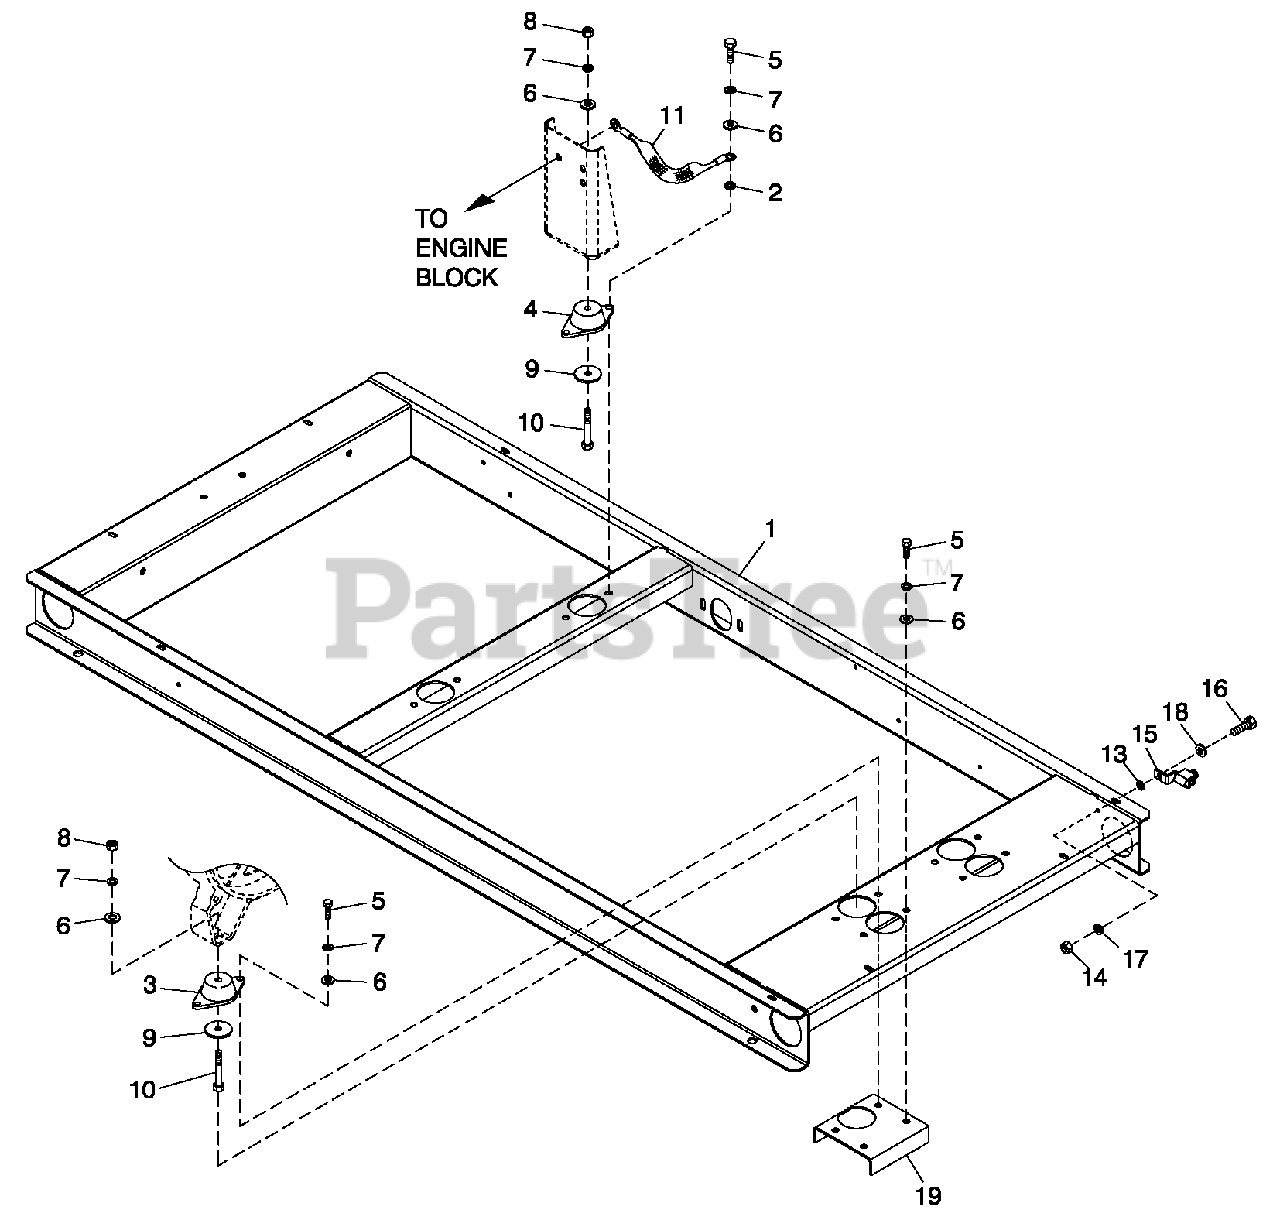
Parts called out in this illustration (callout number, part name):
1	MOUNTING BASE1.6L 2007 C1
2	WASHER SHAKEPROOF EXT 5/16 STL
3	DAMPENER VIBRATION
4	VIB. ISO. 70-75 DURO
5	SCREW HHC M8-1.25X 20 G8.8
6	WASHER FLAT 5/16 ZINC
7	WASHER LOCK M8-5/16
8	NUT HEX M8-1.25 G8 YEL CHR
9	WASHER FLAT M8
10	SCREW HHC M8-1.25X 60 G8.8
11	EARTH STRAP
13	WASHER SHAKEPROOF EXT 1/4 STL
14	NUT HEX M6 X 1.0 G8 YEL CHR
15	LUG SLDLSS #2-#8X 17/64 CU
16	SCREW HHC M6-1.0X 16 G8.8
17	WASHER LOCK M6-1/4
18	WASHER FLAT 1/4-M6 ZINC
